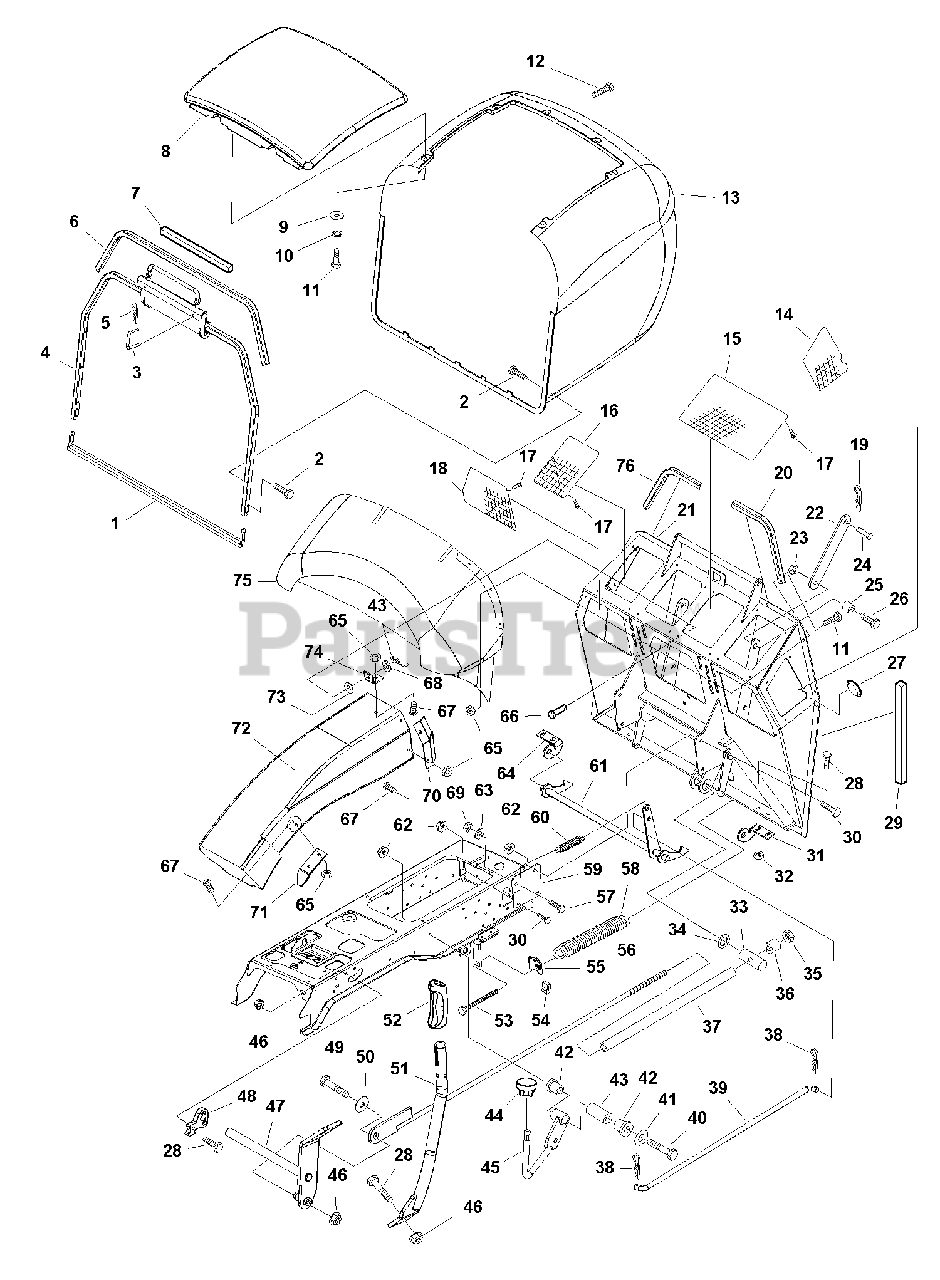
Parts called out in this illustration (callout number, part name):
1	ANGLE & BAR ASSEMBLY
2	CAPSCREW, Hex Head Taptite, 1/4-20 x 1/2
3	PIN, Retaining
4	FRAME ASSEMBLY, Hopper
5	PIN, Quick
6	SEAL, Hopper Frame
7	SEAL, Hopper Lid
8	LID, Plastic Hopper
9	WASHER, 1/4
10	LOCKWASHER, 1/4
11	CAPSCREW, Hex Head, 1/4-20 x 3/4
12	SCREW, Phillips Head, #10-24 x 3/4
13	HOPPER, Plastic, w/Screen
14	SCREEN, Side, 5" x 6.2"
15	SCREEN, Top Middle, 7-1/2" x 11-3/4"
16	SCREEN, Top Side, 5-1/2" x 7-3/4"
17	FASTNER, Panel
18	SCREEN, Main, 7" x 9"
19	CLIP, Spring
20	BRACKET, Hopper Seal, LH
21	BACKPLATE ASSEMBLY
23	NUT, Hex Lock ESNA, 3/8-16
24	PIN, Round Head, Drilled, 1/2 x 1-1/2
26	CAPSCREW, Hex Head, 3/8-16 x 1-1/4
28	CAPSCREW, Hex Head, 5/16-18 x 1
29	SEAL, Hopper Sides
30	CAPSCREW, Hex Head Whiz Lock, 3/8-16 x 1
31	BRACKET, Latch LH
32	NUT, Hex Flange Lock, 5/16-18
35	NUT, Hex Jam, 1/2-13
38	PIN, Hair
40	CAPSCREW, Hex Head, 3/8-16 x 2-1/2
41	WASHER
45	ROD & TUBE ASSEMBLY
46	NUT, Hex KEPS, 5/16-18
47	HANDLE & SHAFT ASSEMBLY
49	CAPSCREW, Hex Head, 5/16-18 x 2-1/4
50	WASHER
51	HANDLE & BRACKET ASSEMBLY
53	CAPSCREW, Hex Washer Head, 5/16-18 x 4-1/2
54	NUT, Speed, 5/16-18
56	ROD & BRACKET ASSEMBLY
57	CAPSCREW, Hex Head, 1/2-13 x 1
58	SPRING, Extension
59	SUPPORT, Backplate
60	SPRING, Extension
61	SHAFT & LATCH ASSEMBLY
62	NUT, Hex Flange Lock, 3/8-16
63	LOCKWASHER, 1/2
64	BRACKET, Latch, RH
65	NUT, Hex Lock ESNA, 1/4-20
67	SCREW, Torx Head, 1/4-20 x 5/8
69	NUT, Hex, 1/2-13
70	DEFLECTOR, Grass
73	NUT, Push
76	BRACKET, Hopper Seal, RH
